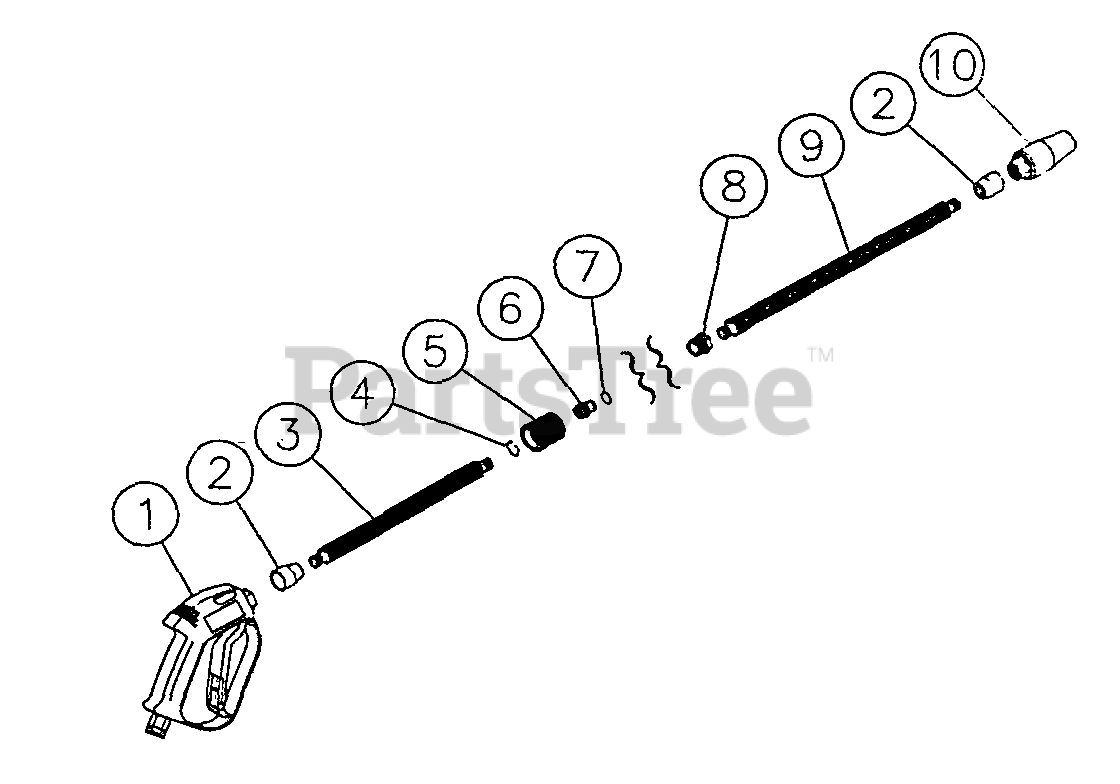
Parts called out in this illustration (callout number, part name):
1	Gun Assembly
2	Protective Cover
3	Insulated Lance
4	Retaining Ring
5	Hand Wheel
6	Plug/Screw Connect
9	Insulated Lance
10	Variable Nozzle (1.2mm)
